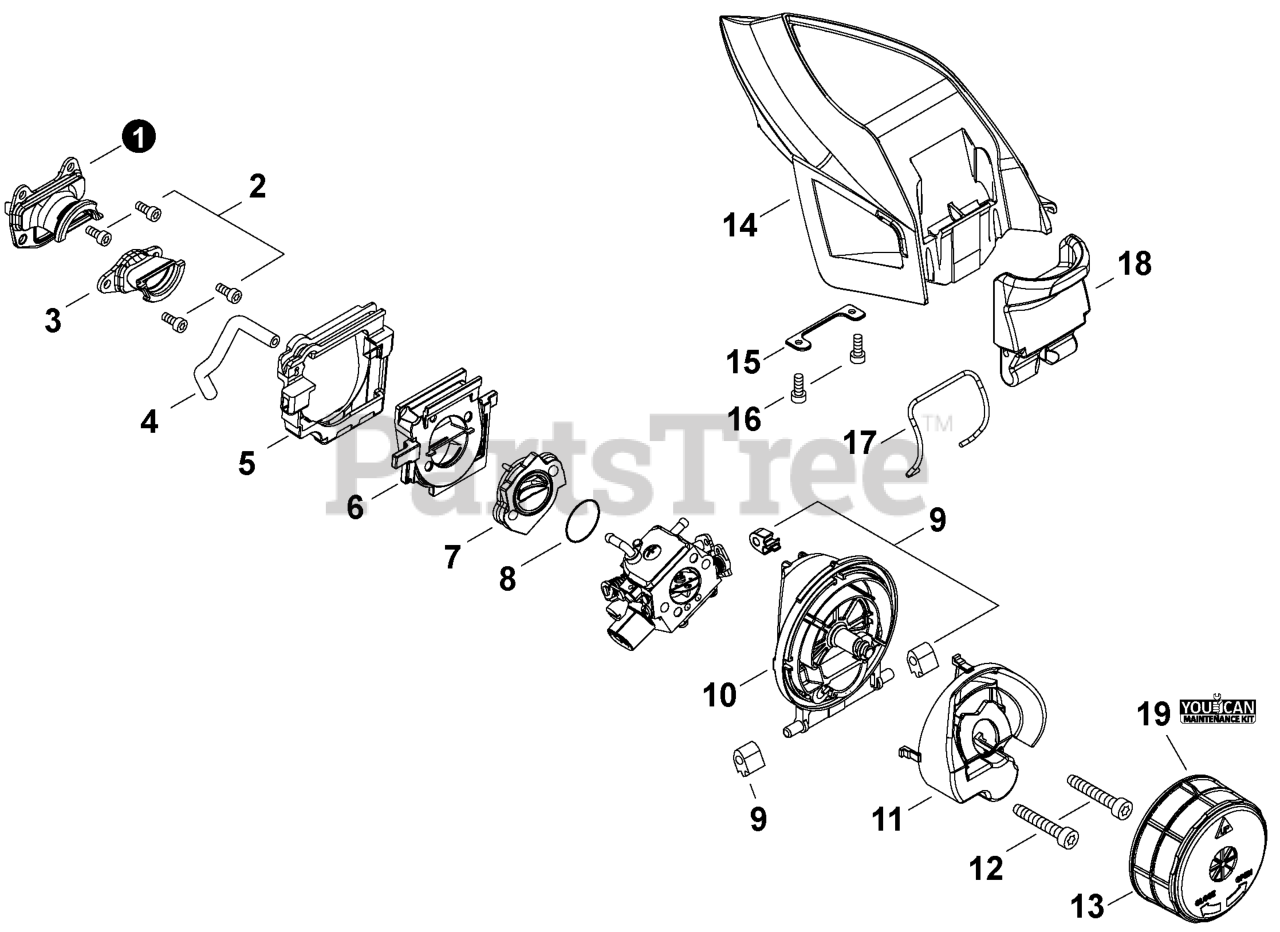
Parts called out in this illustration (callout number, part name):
1	BELLOWS, INTAKE
2	BOLT, TORX 4x12
3	BELLOWS, INTAKE
4	PIPE 3x6x90 MM
5	CUSHION
6	INSULATOR, INTAKE
7	INSULATOR, INTAKE
9	CUSHION
10	CASE, AIR FILTER
11	DUCT, AIR
12	BOLT, TORX 5x55
13	FILTER, AIR
14	COVER, AIR FILTER
15	SPRING, FLAT
16	BOLT, TORX 4x12
17	RETAINER
18	LATCH, COVER
19	TUNE-UP KIT - YOUCANT
